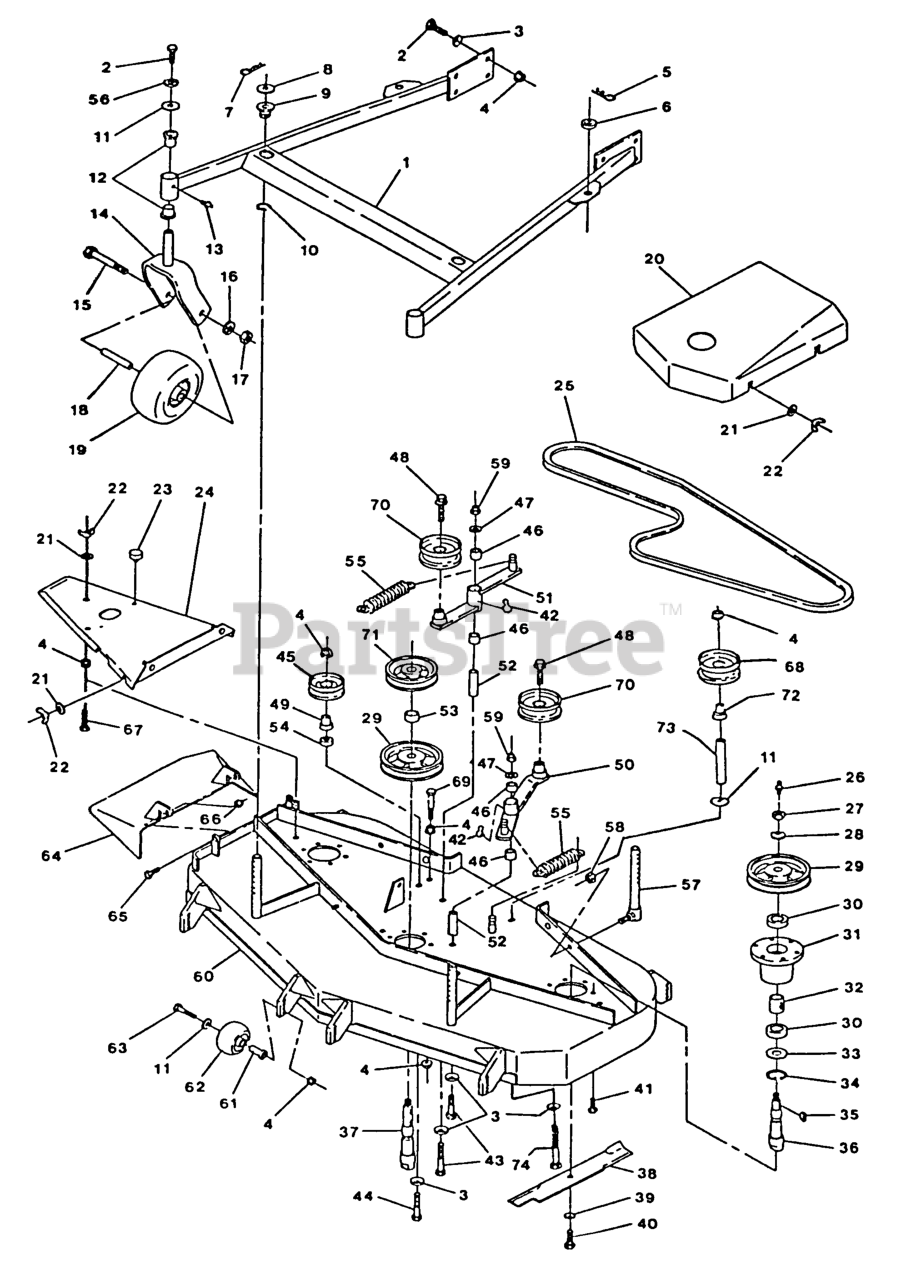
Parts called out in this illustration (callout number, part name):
5	PIN,HAIR COTTER
8	WASHER-FLAT
9	BUSHING-DECK
22	NUT-WING
24	WLD,DECK COVER
25	BELT-DRIVE, BLADE
28	WASHER-SPRING
29	SHEAVE,BLADE DRIVE
32	SPACER,BEARING
33	SEAL,MECHANICAL DUST
34	RING,SNAP WLDS N5000-244
36	SPINDLE-OUTER BLADE
37	SPINDLE-CENTER BLADE
39	Washer-Spring Disc 1/2
41	SCRW,TPTTE HH
43	SCREW-HH
46	SLEEVE-BEARING
49	BUSHING-IDLER
50	Arm Weldment Deck Drive Idler
51	Arm Weld - Dk. Idler Arm
52	BUSHING-PIVOT, IDLER
53	SPACER-TUBE
55	SPRING-EXTENSION
61	BUSHING-ROLLER
62	ROLLER-SCALP, ANTI
63	SCRWCAPHH
68	PULLEY-IDLER
70	IDLER,PULLEY
72	BUSHING,IDLER
73	SPACER-FENDER
